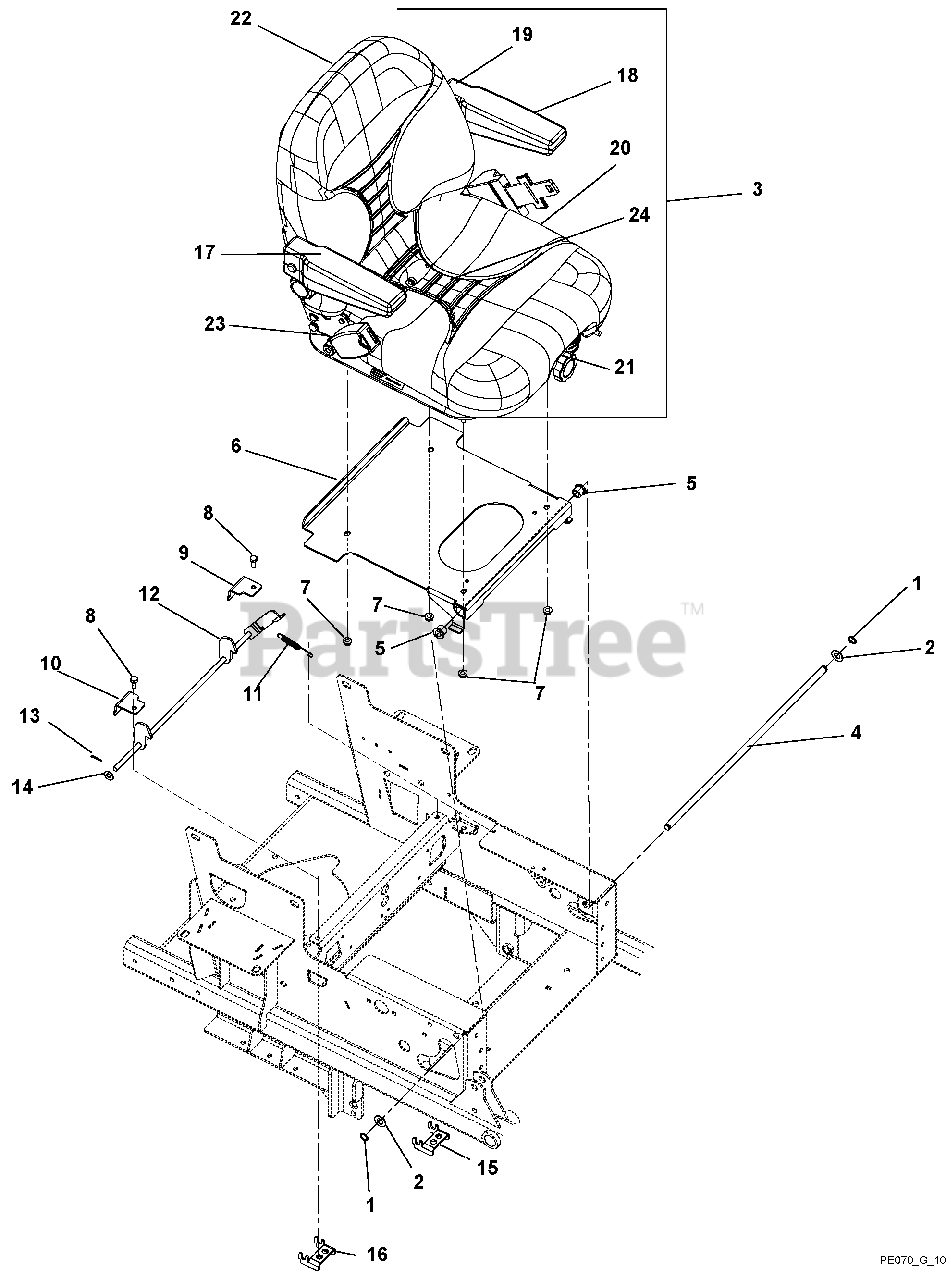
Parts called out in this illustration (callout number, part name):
1	Ring, Retaining-External .500 x .050
2	Washer, Flat Steel .531 x 1.00 x .063
3	Seat, Suspension - with Belt, Light Gray
4	Shaft, 100I Seat Pivot
5	Bushing, Flange .516 x .750 x .625 x .937
6	Seat Plate Weldment
7	Nut, Locking-Top-Flange .31-18
8	Bolt, Hex .31-18 x .75
9	Pro-Turn 100 Left Hand Top Seat Latch Mount
10	Pro-Turn 100 Right Hand Top Seat Latch Mount
11	Spring, Tension .043 x .44 x 3.31
12	Pro-Turn 100 Seat Latch Weldment
13	Pin, Center .09 x .75 Extended Prong Square Cut
14	Washer, Flat-Steel .406 x .812 x .065
15	Pro-Turn 100 Right Hand Seat Latch Mount Weldment
16	Pro-Turn 100 Left Hand Seat Latch Mount Weldment
17	Kit, Right Hand Armrest Assembly
18	Kit, Left Hand Armrest Assembly
19	Kit, Back Cushion, Light Grey
20	Kit, Seat Cushion, Light Grey
21	Kit, Seat Knobs
22	Kit, Seat Back
23	Kit, Seat Slides
24	Kit, Seat Spring and Saddle
